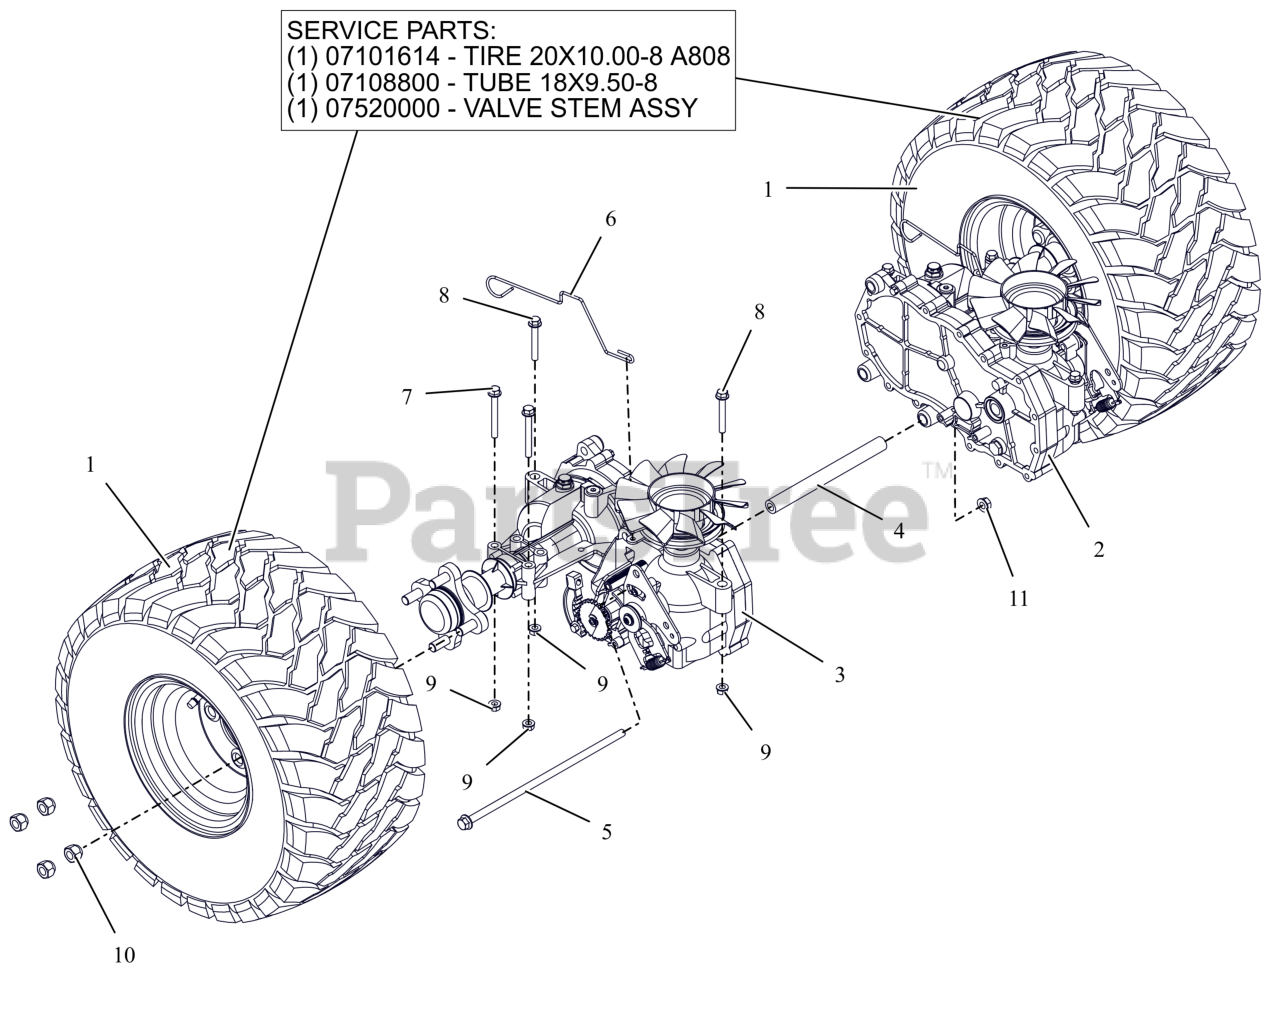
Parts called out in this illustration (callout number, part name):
1	ASM-WHL/TIRE 20X10.00-10 K505
1	TIRE 20X10.00-8 A808 TREAD
1	VALVE STEM ASS'Y
1	TUBE 18X6.50/8.50/9.50-8/20X8.00/10.00-8
2	TRANSAXLE- SERVICEABLE EZT -LH
3	TRANSAXLE- SERVICEABLE EZT -RH
4	SPCR, TRANSAXLE .438 ID X .750 OD X 8.18 (BLACK)
5	BLT, HEX-FLG 0.375-16X11.5 GR5 ZC120
6	WIRE- DUMP VALVE LEVER
7	BLT,HEX-FLG .31-18X2.75 G5 ZCC
8	BLT,HEX-FLG .31-18X2.25 G5 ZCC
9	NUT,LK-CTR-FLG .31-18 GF ZCC
10	NUT, WHEEL .50-20 ZCC
11	NUT-LK-CTR-FLG .375-16 GF ZCC
